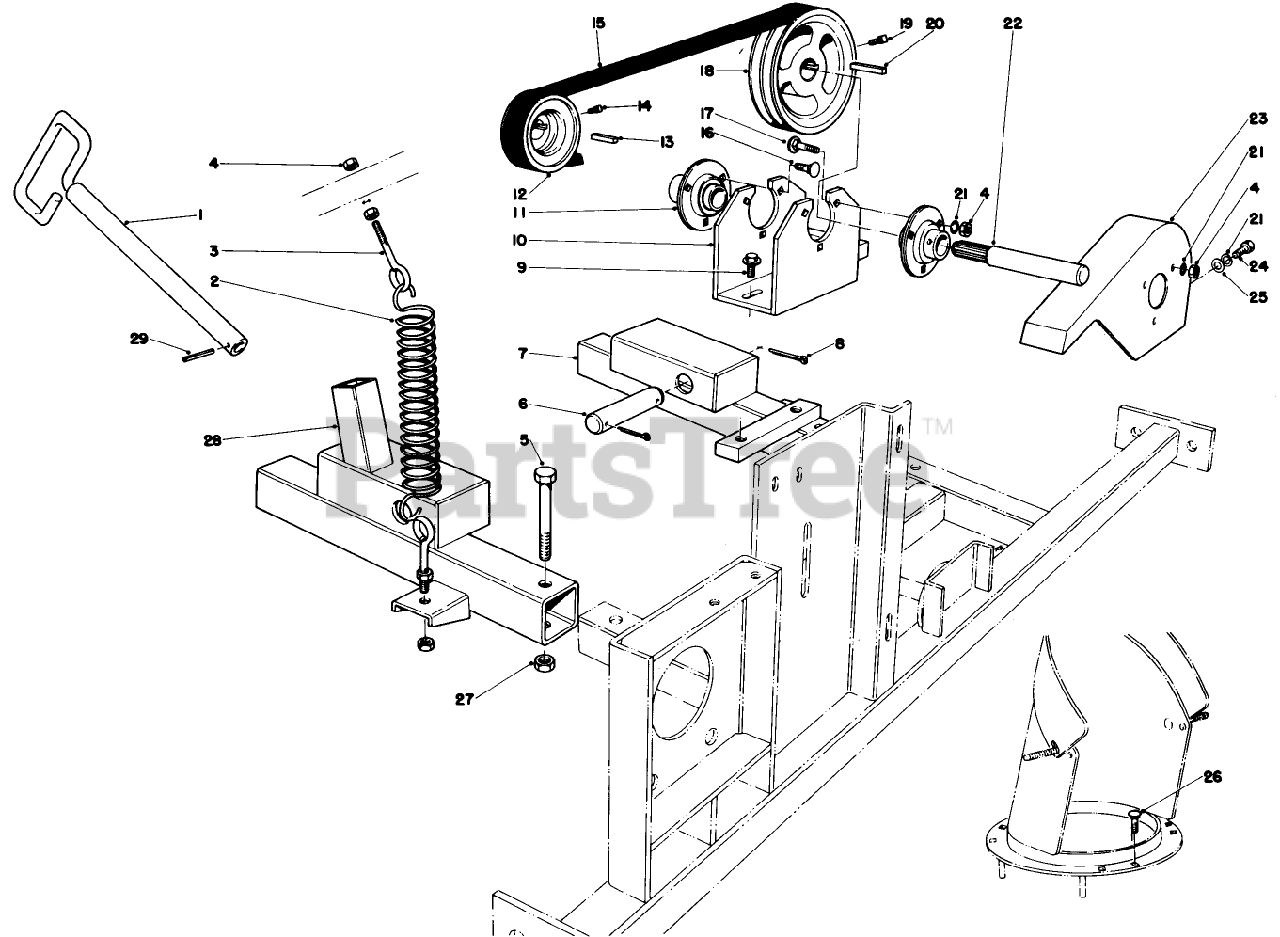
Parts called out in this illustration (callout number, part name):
1	Chute Pivot Handle
2	Extension Spring
3	Eyebolt
4	NUT-HEX
5	SCREW-HH
7	Adapter L.H.
8	3/32 X 1-3/4 LG COTTER
9	SCREW-HHF
10	JACKSHAFT SUPPORT
11	Bearing
12	JACKSHAFT PULLEY
14	SCREW-SET, SQH
15	V-BELT
16	SCREW-CARR
17	BOLT-CARR
18	JACKSHAFT PULLEY
19	SCREW-SET, SQH
21	WASHER-LOCK/SP
22	Jackshaft
23	Belt Shield
24	SCREW-HH
25	WASHER-PLAIN
26	SCREW-CARR
27	NUT-LOCK, CONE
28	Adapter R.H.
29	PIN-SPRING
